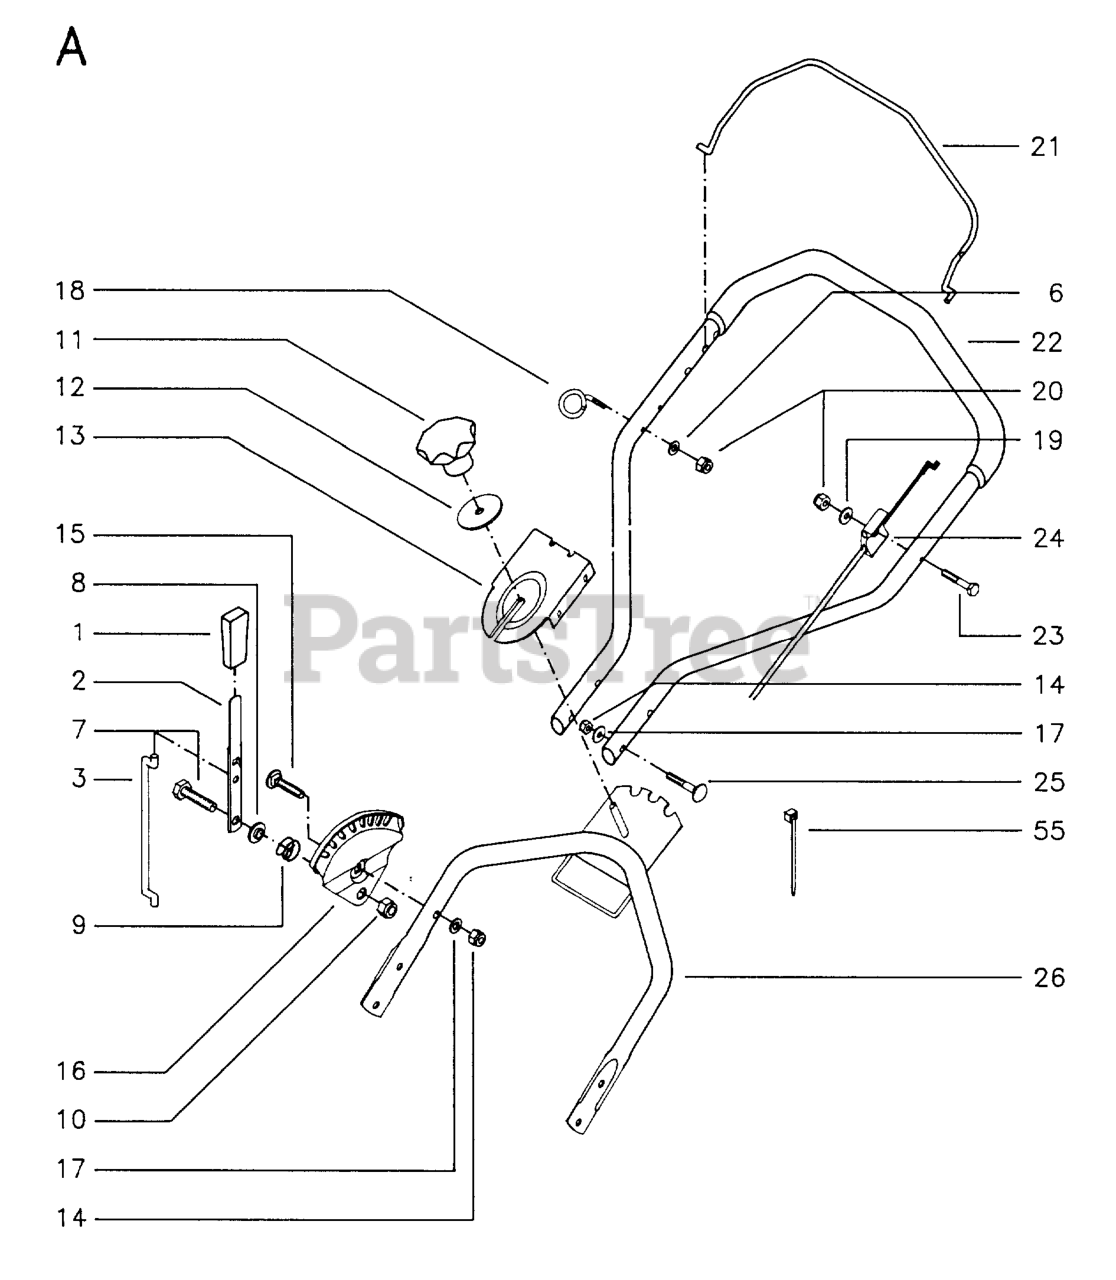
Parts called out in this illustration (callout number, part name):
2	CLUTCH ARM
9	PRESSURE SPRING
14	LOCKNUT M8
16	INDEXPLATE
17	WASHER - 15X7.3X1.6
18	CABLE GUIDE
20	LOCKNUT M6
23	BOLT FLANGE
